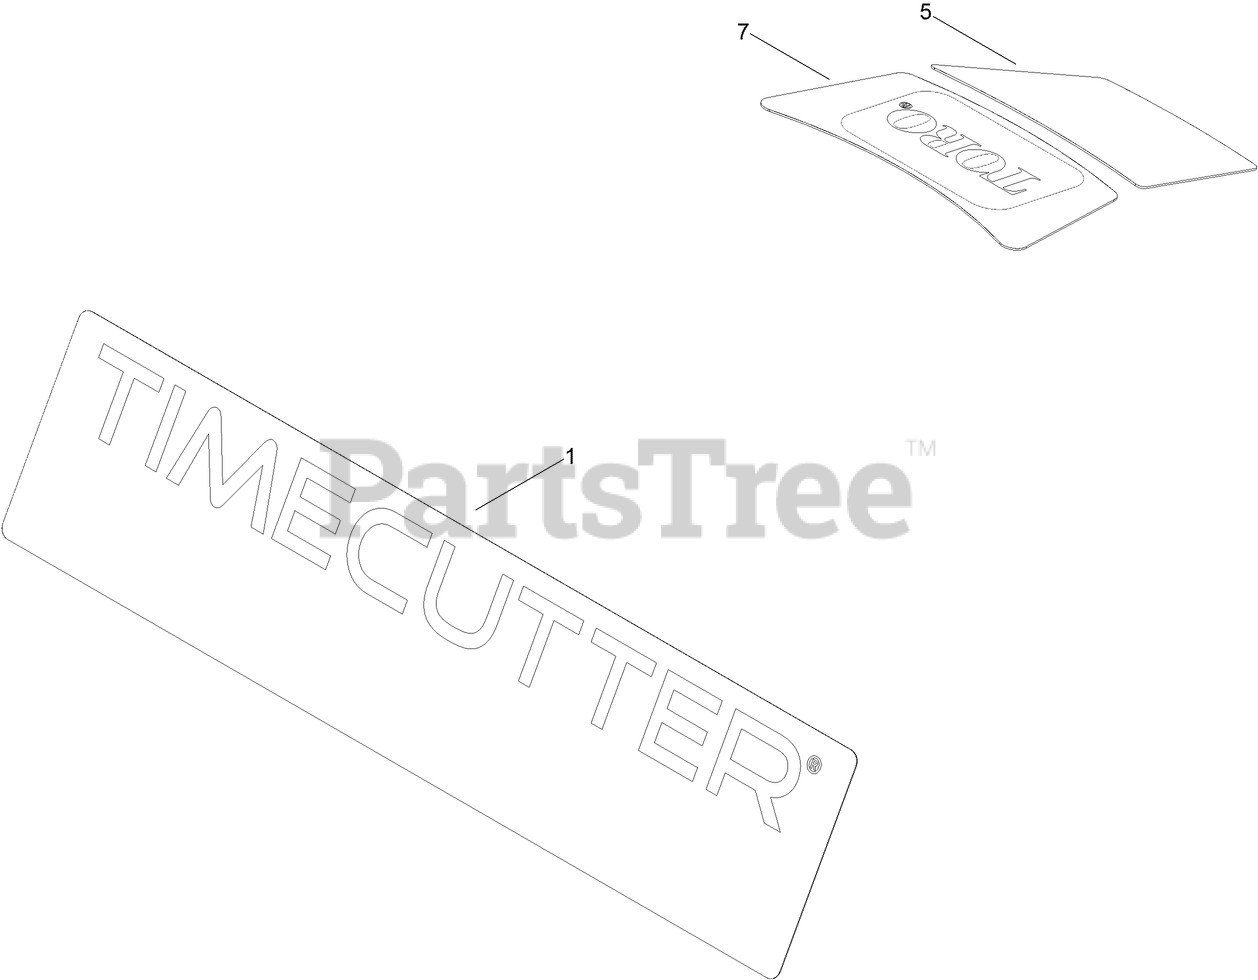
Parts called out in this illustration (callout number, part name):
1	DECAL-TIMECUTTER
5	DECAL-DISPLACEMENT, ENGINE
7	DECAL-ENGINE
